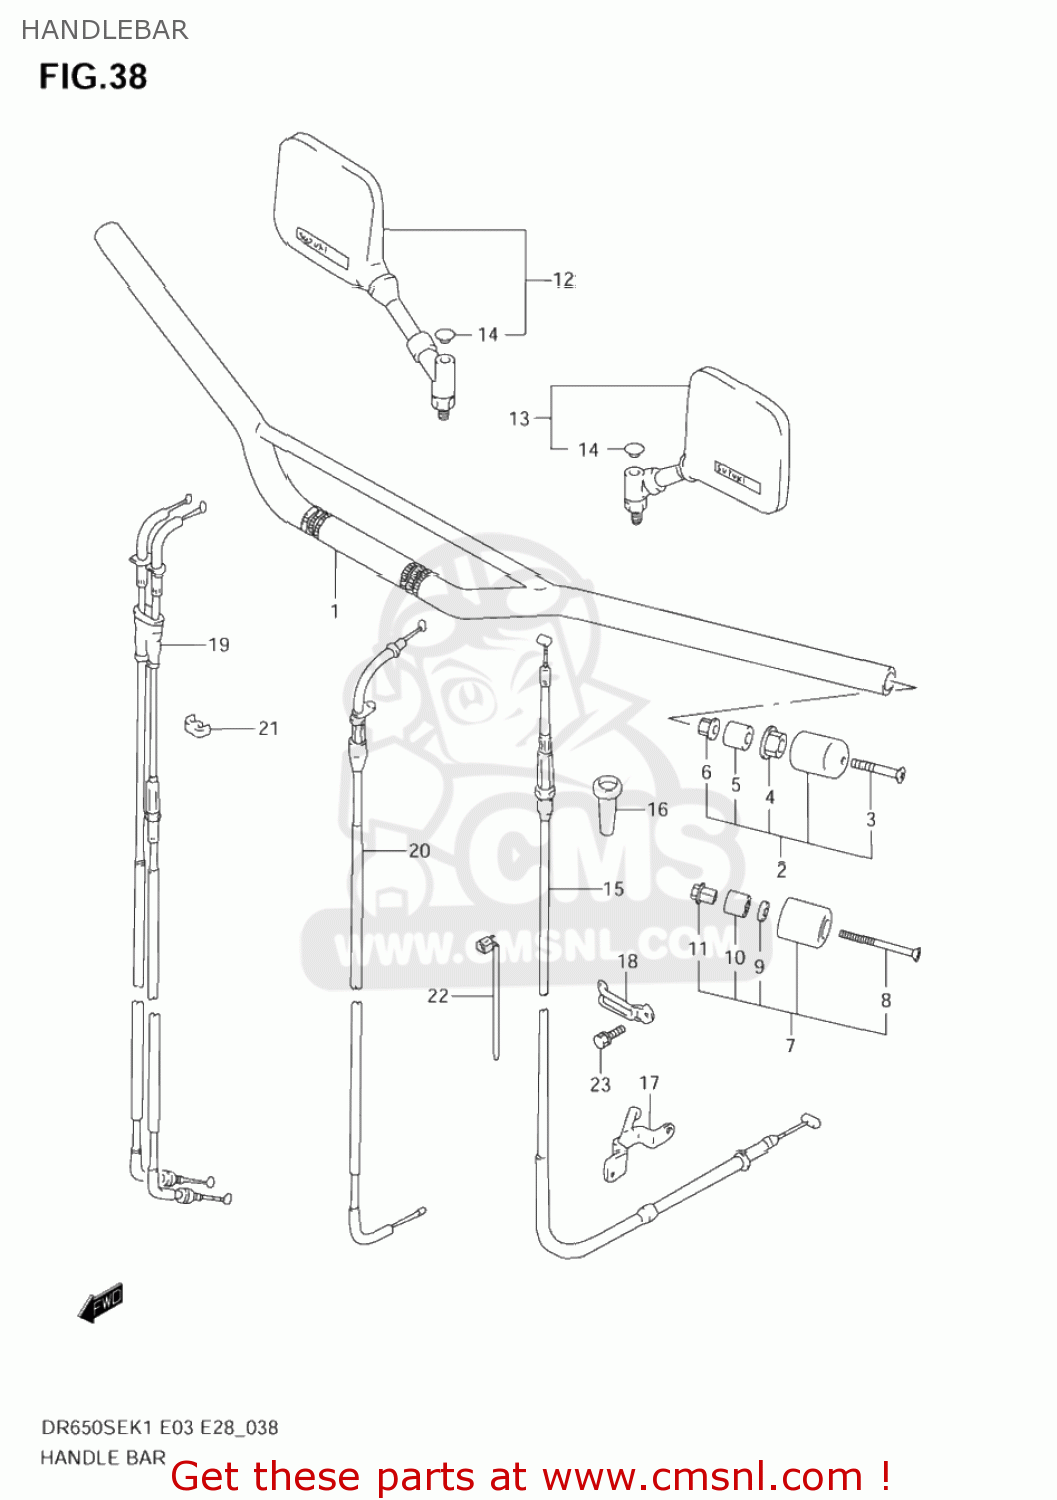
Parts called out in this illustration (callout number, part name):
1	HANDLEBAR(BLACK)
2	BALANCER SET,HANDLEBAR
3	SCREW
4	NUT
5	EXPANDER,HANDLE BALANCER
6	NUT
7	BALANCER,HANDL
8	SCREW
9	WASHER(6.5X16X4)
10	EXPANDER,HANDLE BALANCER
11	NUT,HANDLE BAL
12	MIRROR ASSEMBLY,REAR VIEW
13	MIRROR ASSEMBLY,REAR VIEW
14	CAP
15	CABLE ASSY,CLUTCH
16	BOOT,CLUTCH CABLE
17	STOPPER,CLUTCH CABLE
18	CLAMP
19	CABLE ASSY,THROTTLE
20	CABLE,STARTER
21	CLIP
22	CLAMP(L:235)
23	BOLT
